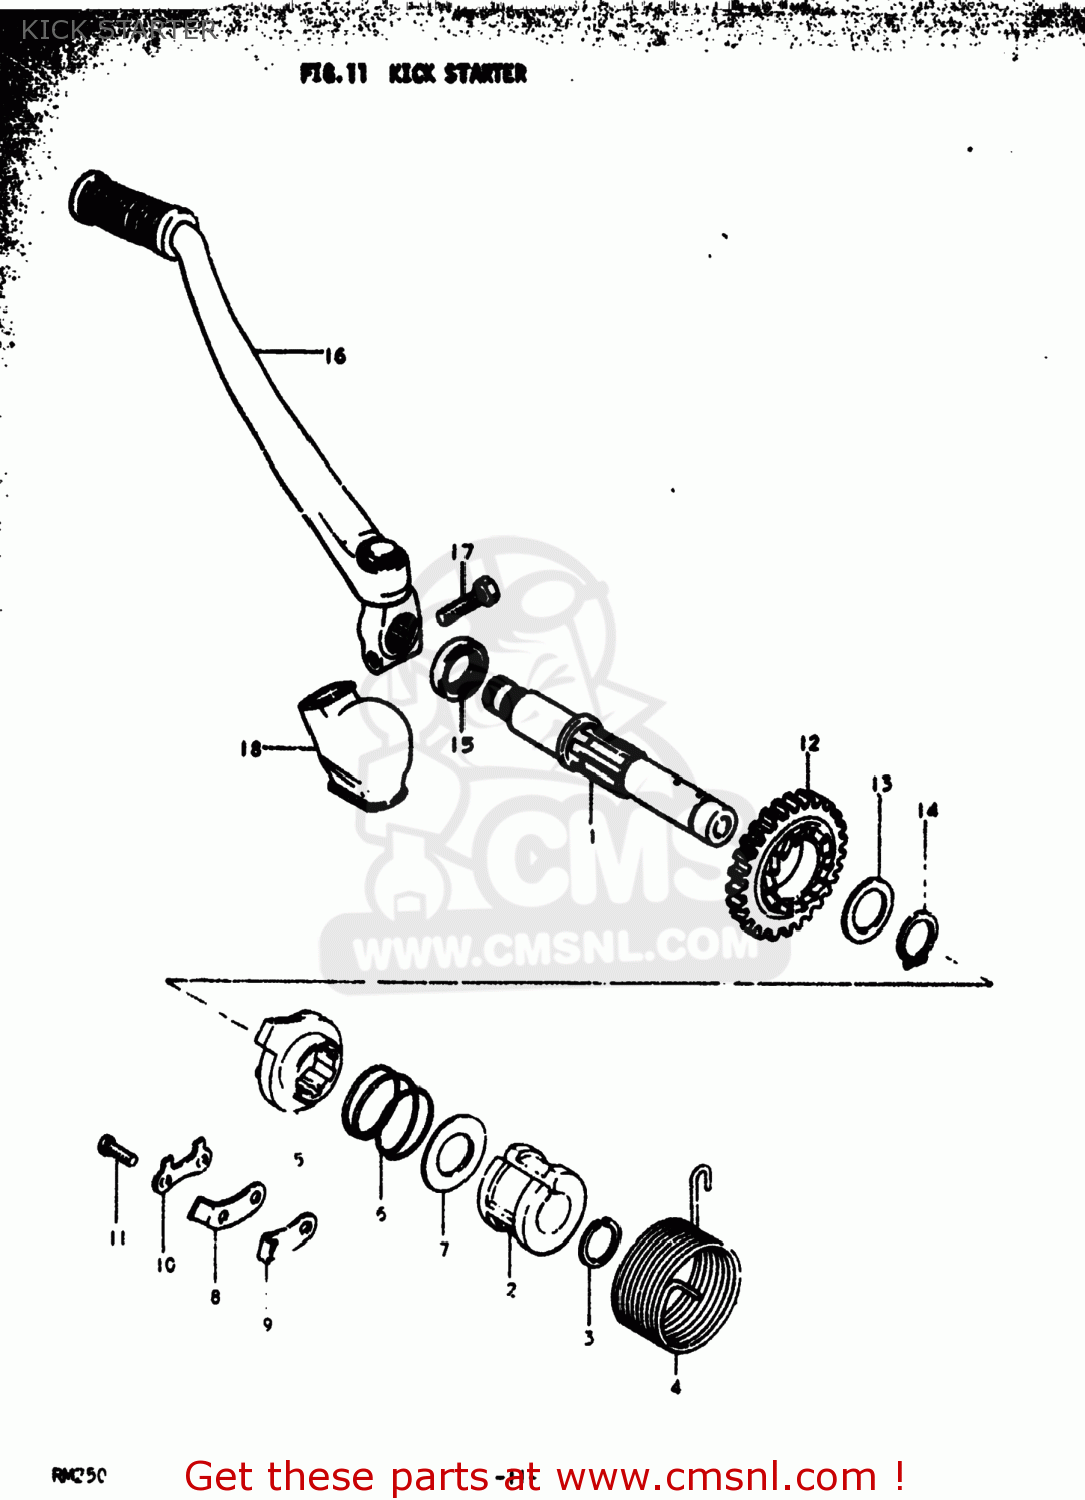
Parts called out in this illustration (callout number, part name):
1	SHAFT,KICK STARTER
2	GUIDE,KICK STARTER SFT SPRING
3	CIRCLIP
4	SPRING
5	STARTER,KICK
6	SPRING
7	WASHER
8	GUIDE,KICK STARTER
9	STOPPER,KICK STARTER
10	WASHER
11	BOLT, UPPER
12	GEAR,KICK STARTER DRIVE
13	SHIM
14	CIRCLIP
15	OIL SEAL
16	LEVER ASSEMBLY,KICK STARTER
17	BOLT
18	COVER,KICK LEVER JOINT
